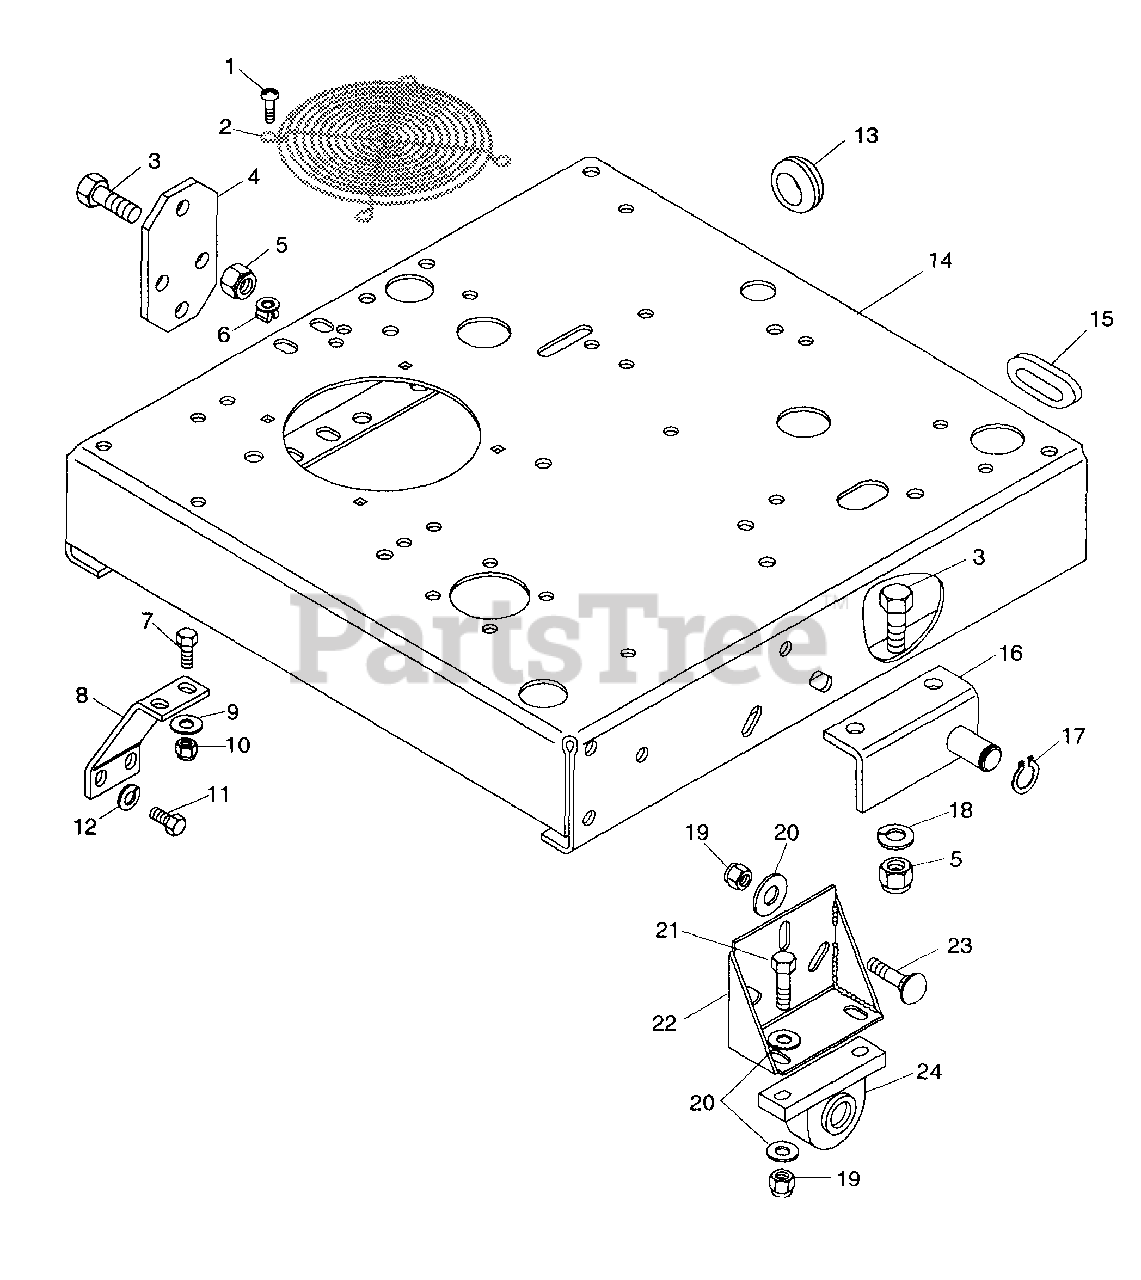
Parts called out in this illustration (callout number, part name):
1	Screw-Tapping .25-20 x .50
2	Guard, Fan
3	Bolt-Hex .50-13 x 1.50 Grade 5
4	Plate
5	Nut-Locking-Nylon .50-13
6	Grommet, Plastic
7	Bolt-Hex .31-18 x 1.00 Grade 5
8	Bracket, Transaxle Support
9	Washer-Flat-Steel .344 x .688 x .065
10	Nut-Locking-Nylon .312-18
11	Bolt-Hex .31-18 x .75 Grade 5
12	Washer-Lock .313 x .078
13	Grommet 1.50 x 1.75 x 2.12
14	Weldment, Frame
15	Grommet .63 x .687 x 1.25
16	Weldment, Pivot Left Hand
16	Weldment, Pivot Right Hand
17	Ring-Retaining-External .689 x .077
18	Washer-Lock .50
19	Nut-Locking-Nylon .375-16
20	Washer-Flat-Steel .406 x .812 x .065
21	Bolt-Hex .38-16 x 1.50 Grade 5
22	Weldment, Axle Support
23	Bolt-Round Head Square Neck .38-16 x 1.00
24	Bearing, Pillow Block 1.0 x 2.688 x 6.188
